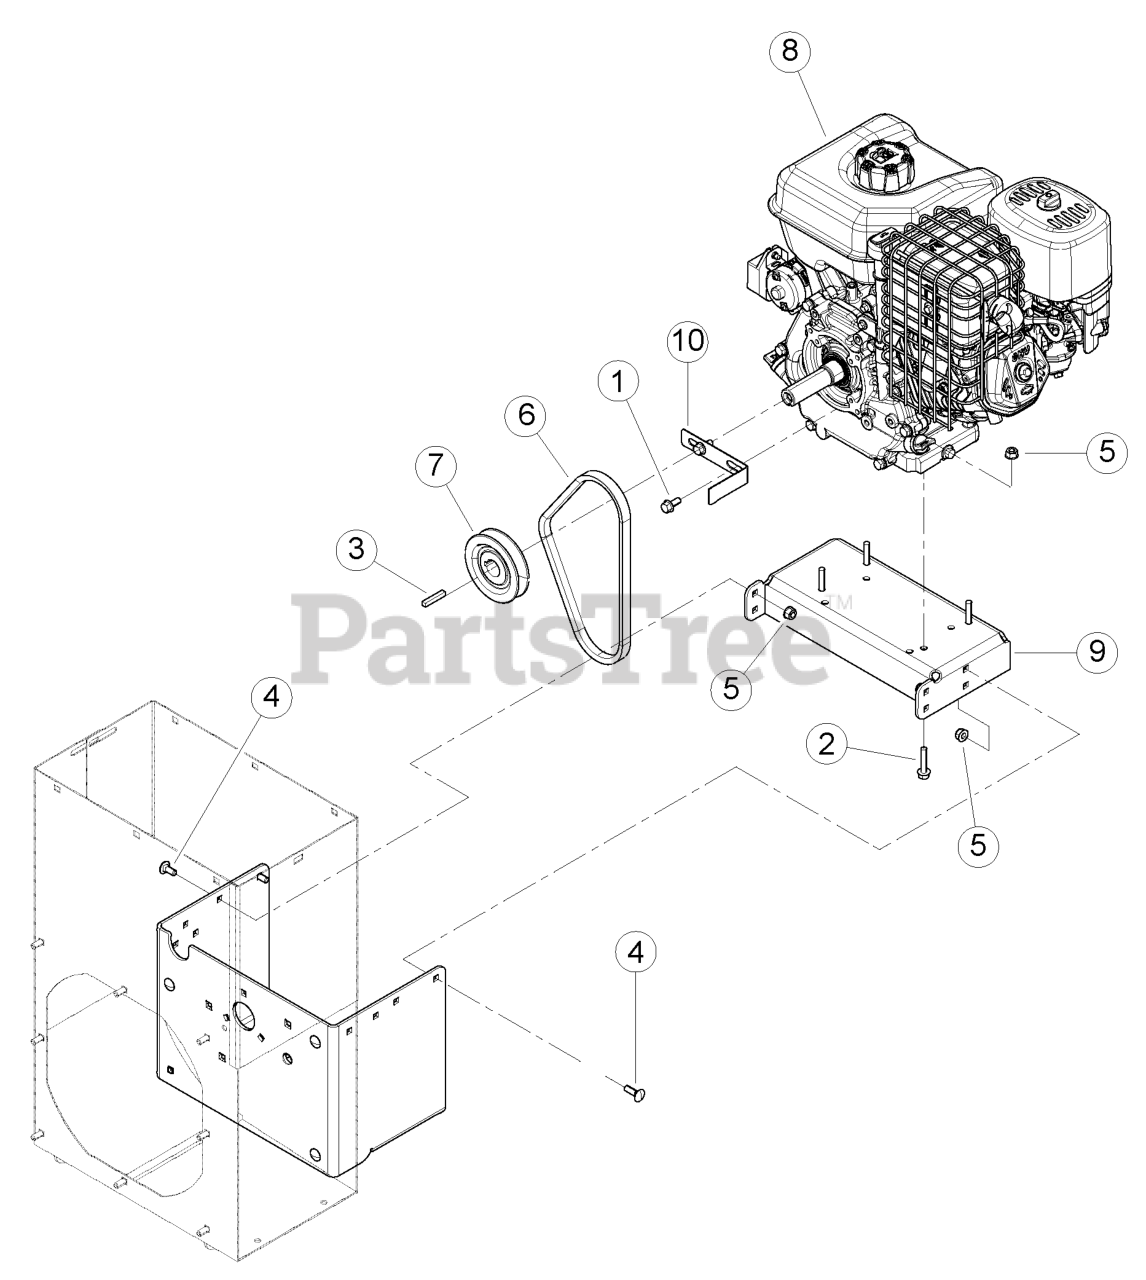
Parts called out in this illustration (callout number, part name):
1	BOLT, 5/16 × 3/4 SERRATED FLANGE NF
2	BOLT, 5/16 × 1-1/2 FLANGE NC
3	KEY, 1/4 SQ × 1-1/2 LG PLAIN
4	BOLT, 5/16-18 × 1 GR5 CRG
5	NUT, 5/16-18 NYLOCK FLANGE
6	BELT, 29" C/S
7	PULLEY, CAST 4" OD 1" BORE B GRV
8	ENGINE, 306cc B&S HORIZONTAL
9	PLATE, ENGINE MOUNTING
10	GUIDE, BELT
